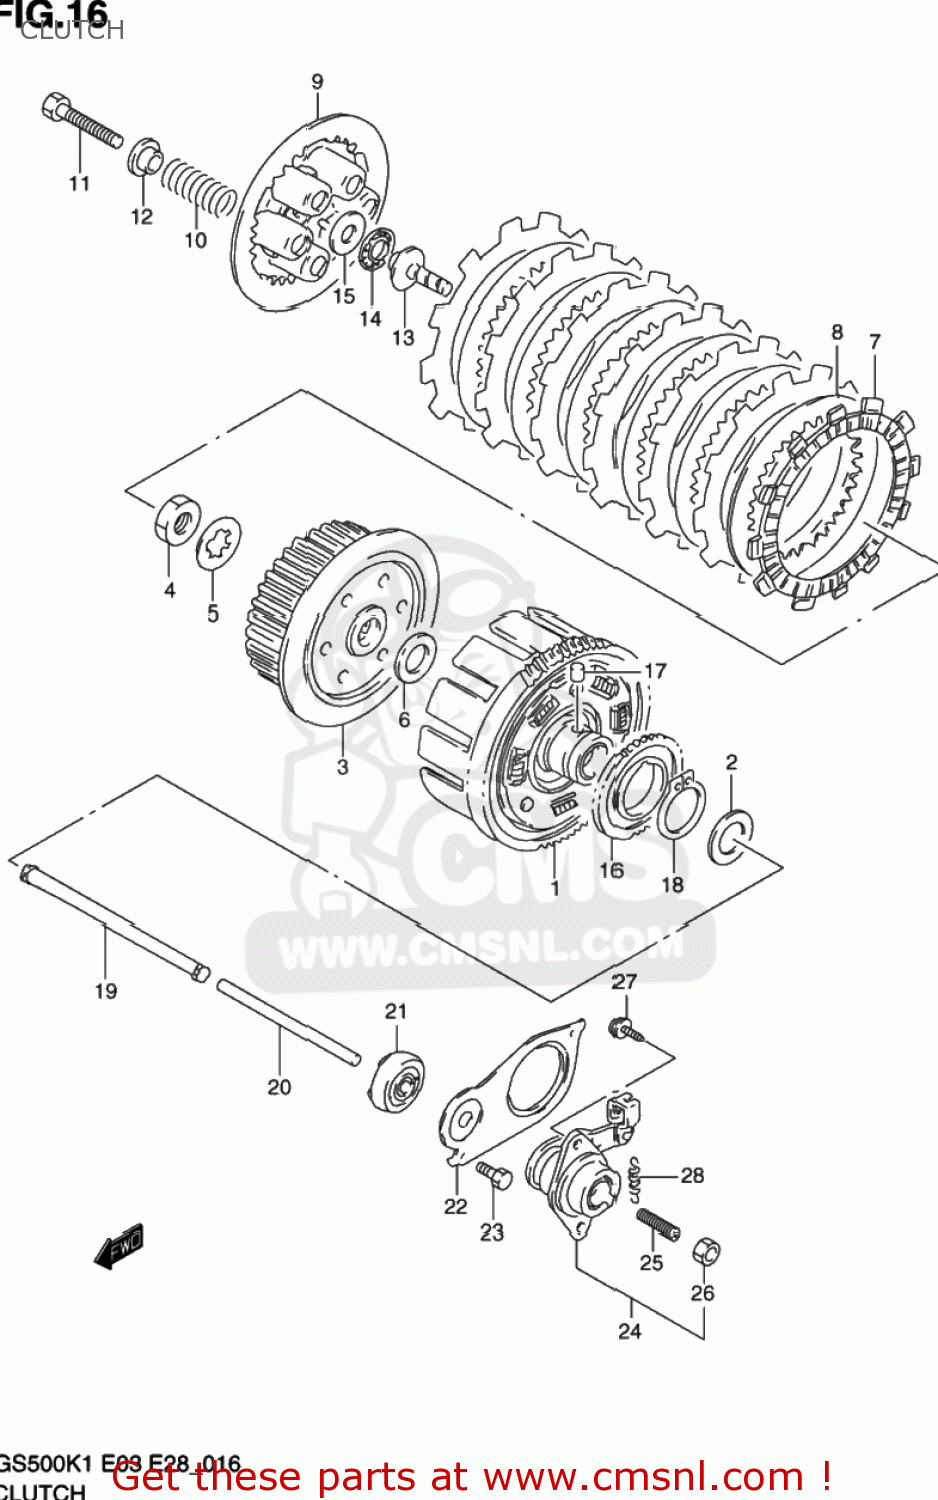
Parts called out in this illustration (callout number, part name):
1	GEAR ASSY,PRI DRIVEN
2	SHIM(25X38X1)
3	HUB,CLUTCH SLEEVE
4	NUT
5	WASHER,LOCK
6	WASHER(20X44X3)
7	PLATE,CLUTCH DRIVE (NAS)
8	PLATE,CLUTCH DRIVEN(T:1.6) (NAS)
9	DISC,CLUTCH PRESSURE
10	SPRING
11	BOLT(6X40)
12	SPACER,CLUTCH SLEEVE HUB
13	PIECE,CLUTCH PUSH
14	BEARING(15X28X2)
15	WASHER(15.5X28X1)
16	GEAR,OIL PUMP DRIVE(NT:39)
17	PIN(6X6)
18	CIRCLIP
19	ROD,PUSH,R
20	ROD,CLUTCH PUSH,L
21	SEAL,OIL(6X34X10)
22	RETAINER,PUSH ROD OIL SEAL
23	BOLT
24	SCREW ASSY,CLUTCH RELEASE
25	SCREW(6X25)
26	NUT
27	SCREW 6X16
28	SPRING
